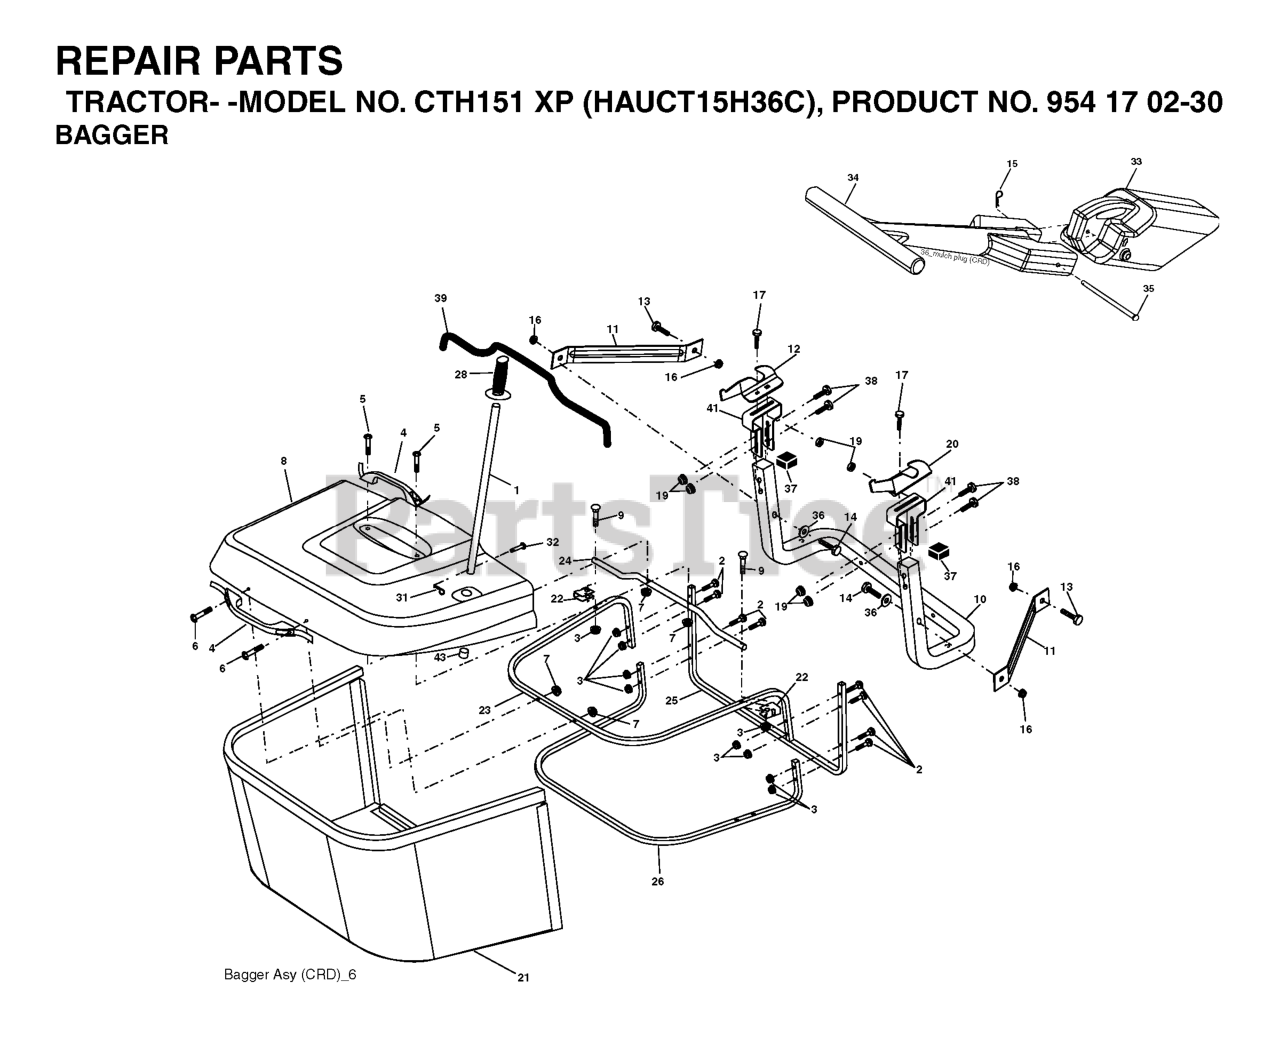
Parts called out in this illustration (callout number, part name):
1	TUBE HANDLE
2	Bolt Carriage 1/4-20 x 2.0 Gr.5
3	NUT T
4	HANDLE.BAGGER.W/LVRS.BLK.CRD
5	SCREW.PAN.HEAD
6	REPL BY 532 75 00-29
8	COVER.PNT.BGR.CRD.WSLOTS.MS668
9	Bolt Carriage 1/4-20 x 2.25d x Gr.5
10	TUBE
11	BRACKET.SUPPORT.UPPER.BAG.CRD
12	BRKT PIVOT
13	BOLT
14	BOLT-HEX EAK
15	RETAINER-SPRNG RB
16	NUT LOCK FLG 3/8-16 UNC
17	RP BOLT 5/16-18 X3/4 ZN/YEL GR
19	NUT LOCK HEX FLANGE 5/16-18
20	BRKT.PIVOT.RH.CRD
21	GRASS BAG
22	BRKT.SIDE.BAG.CRD
23	TUBE.UPPER.BAG.CRD
24	TUBE.PIVOT.BAG.CRD.BLACK
26	TUBE.LOWER.BAG.CRD
28	GRIP.HANDLE.BLACK
31	RETAINER CLIP
32	RIVET,DRILLED
33	PLUG.MULCHER.92 CRD
34	HANDLE.MULCHER.92.CRD (2 2)
36	WASHER
37	Plug Support Bagger CRD
38	BOLT.5/16-18X2.5
39	SEAL.TRIM.37'
41	BRKT.VERT.ADJ.BAGGER.CRD
43	PLUG, TUBING END
